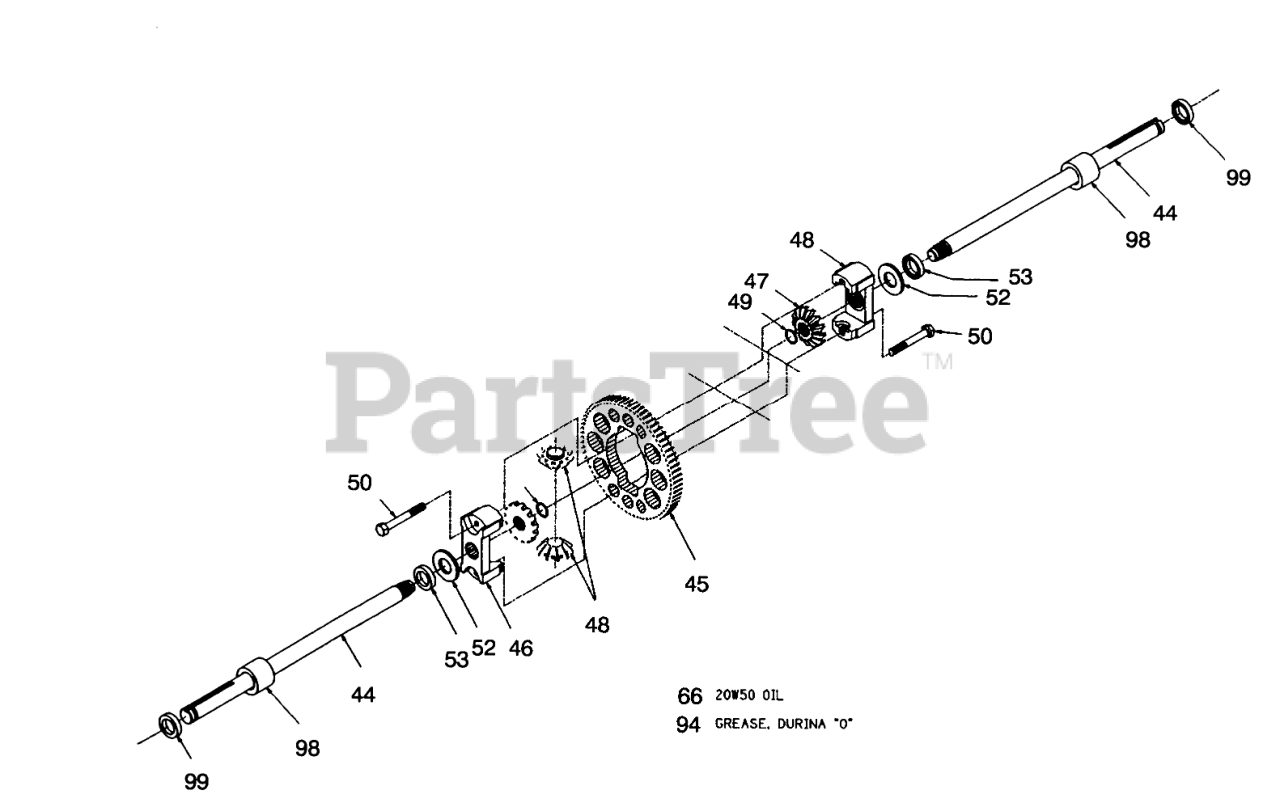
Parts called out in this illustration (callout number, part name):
26	Plate-Bypass
44	Shaft-Axle
46	Housing-Diff.
48	Gear-Planet 1 OT
50	Bolt-Diff. Locking
52	Washer
53	Seal ASM
66	Oil (.5675)
94	Grease Durina "O"
98	Sleeve-Bearing
99	Seal-Wiper
